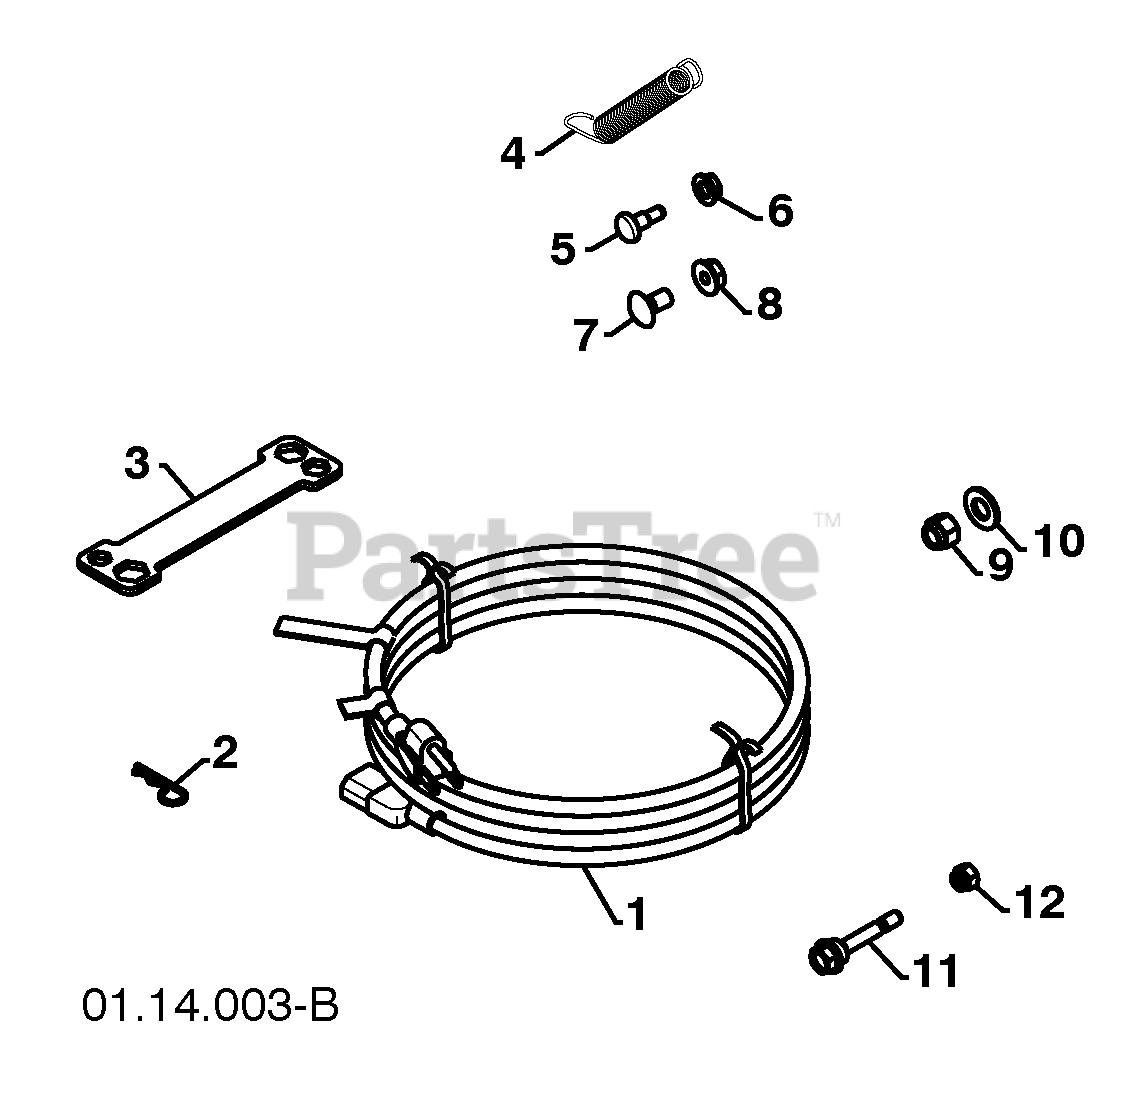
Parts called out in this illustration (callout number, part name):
1	POWER CORD
2	RETAINER PIN
4	REMOTE SPRING
5	SHOULDER BOLT 1/4-20
6	LOCKNUT 1/4-20
7	CARRIAGE BOLT 5/16-18 X 5/8
8	LOCKNUT 5/16-18
9	LOCKNUT 3/8-16
10	WASHER 3/8
11	SHEAR BOLT 1/4-20 X 1-13/16
12	LOCKNUT 1/4-20
